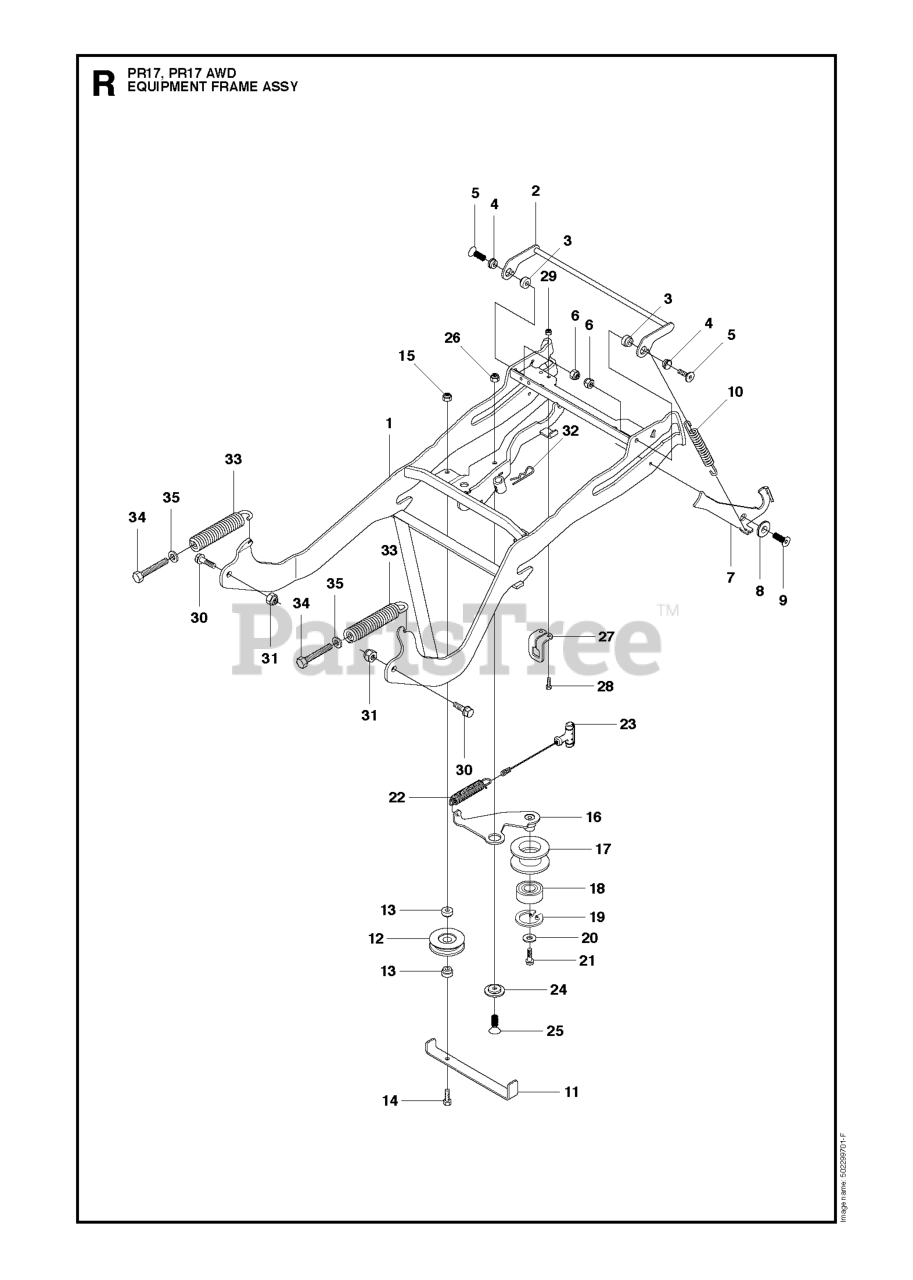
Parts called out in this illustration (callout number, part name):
6	LOCKNUT M8
8	SPACER
9	SCREW IHCSFM
12	PULLEY ASSY
14	SCREW
15	LOCKNUT M8
17	%PULLEY
18	BALL BEARING 6004-2RS1
19	RETAINING RING
24	WASHER
26	LOCKNUT M8
28	BOLT FLANGE - M6X20
29	LOCKNUT M6
35	WASHER
